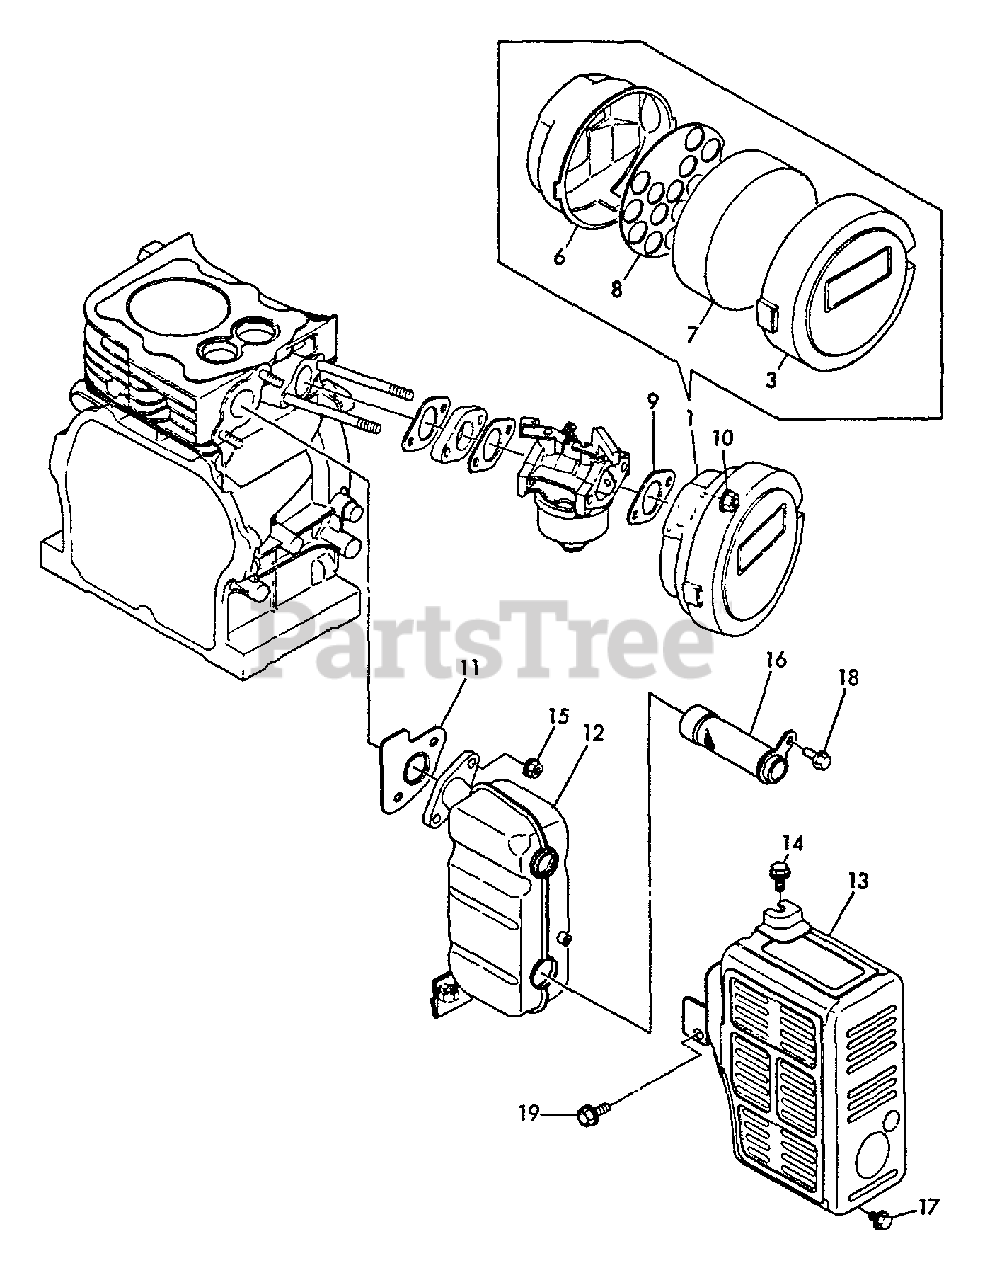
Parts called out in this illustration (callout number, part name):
1	CLEANER ASSY, AIR
3	COVER, AIR FILTER
6	CASE, AIR FILTER
7	FILTER, AIR
8	HOLDER, ELEMENT
9	GASKET, INTAKE
10	U-NUT M6
11	GASKET, EXHAUST
12	MUFFLER
13	COVER, MUFFLER
14	BOLT - 6×8 -- PLATED
15	U-NUT M6
16	SCREEN, SPARK ARRESTER
17	BOLT - 6×8 -- PLATED
18	BOLT - 6×10 -- PLATED
19	BOLT - 8×14 -- PLATED
